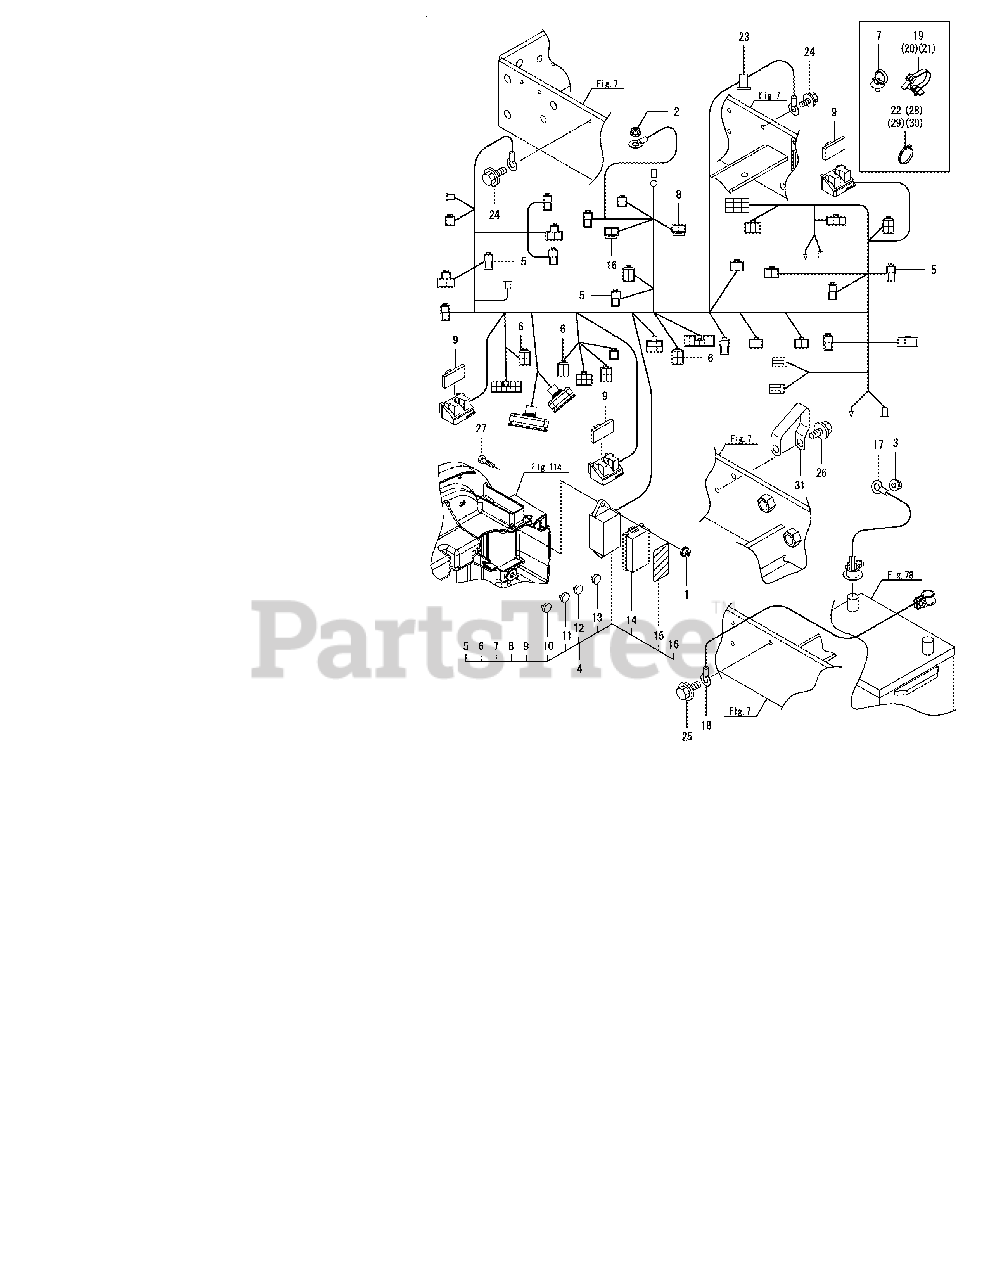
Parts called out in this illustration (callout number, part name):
1	Nut W/Washer 6
2	Nut W/Washer 6
3	Nut W/Washer 8
4	Harness Assy,Wire
8	Blow, Slow Fuse 60A
14	Cover, Fuse Box
16	Blow 79A,Slow Cmp
17	Cable, Battery
18	Cable,Battery Neg.
23	Sticker 18,Wire
24	Bolt M 8X 16 Plated
25	Bolt M 8X 16 Plated
26	Bolt M10X 20 Plated
